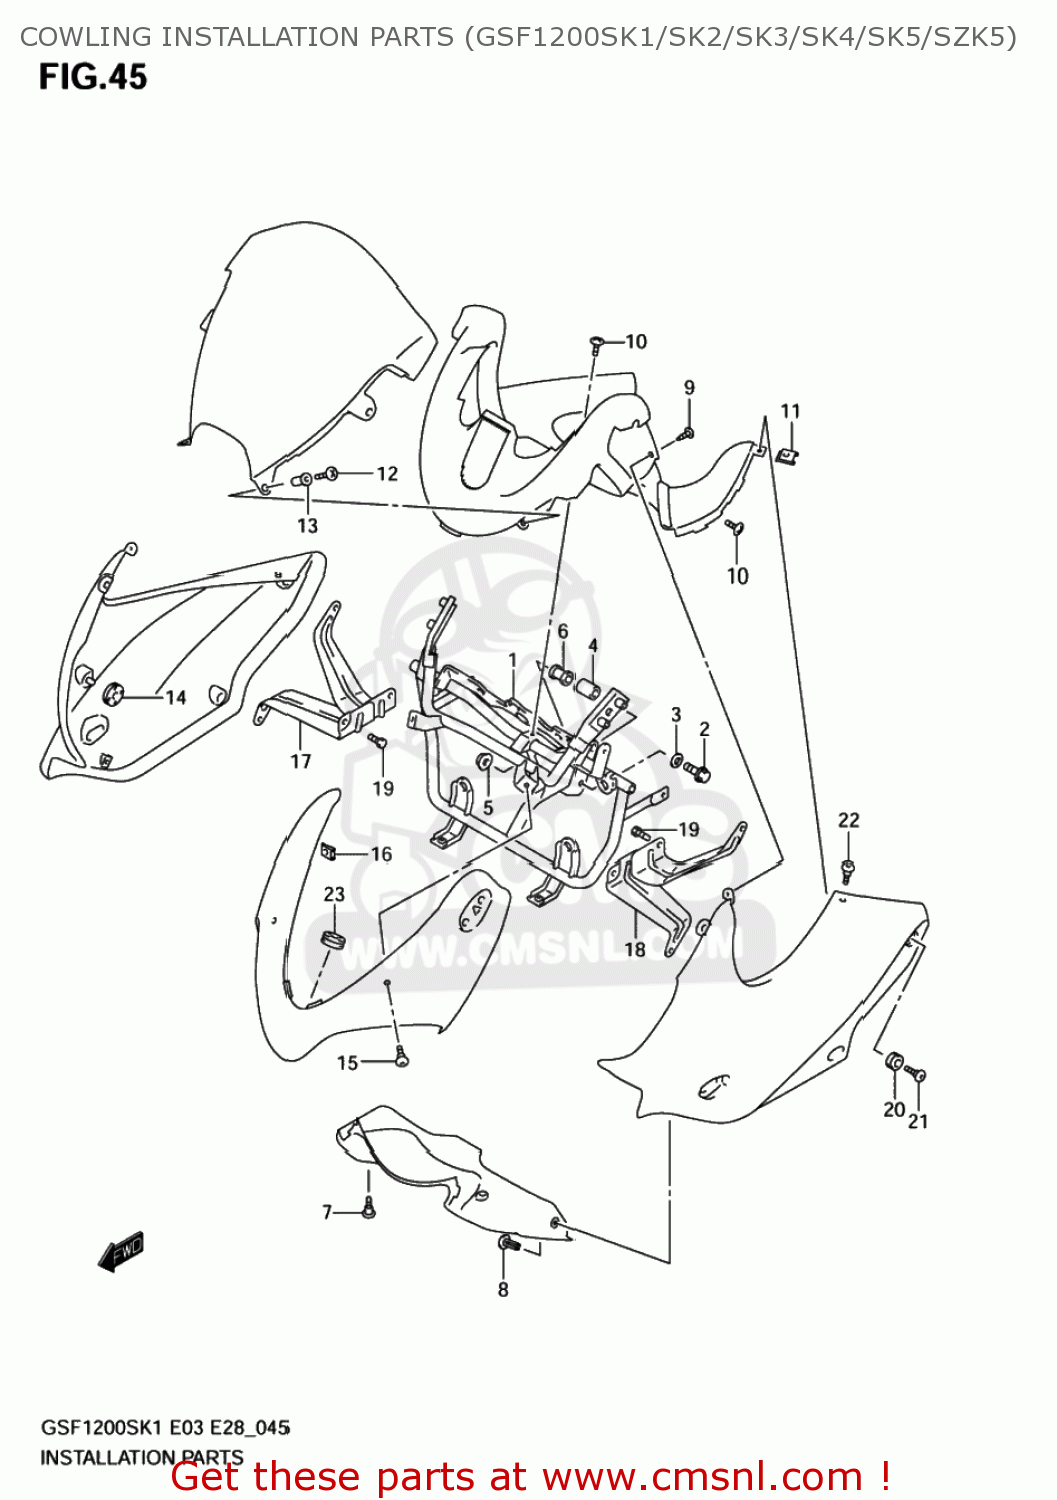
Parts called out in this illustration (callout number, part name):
1	BRACE,COWLING
2	BOLT(8X40)
3	WASHER
4	SPACER
5	NUT
6	CUSHION,COWLING BRACE
7	SCREW(5X16)
8	CLIP(BLACK)
9	SCREW
10	SCREW 5X12
11	NUT,COWL
12	SCREW
13	NUT
14	CUSHION
15	SCREW(5X16)
16	NUT
17	BRACKET COMP,S
18	BRACKET COMP,S
19	BOLT
20	CUSHION
21	SCREW(6X20)
22	SCREW(5X16)
23	CUSHION
